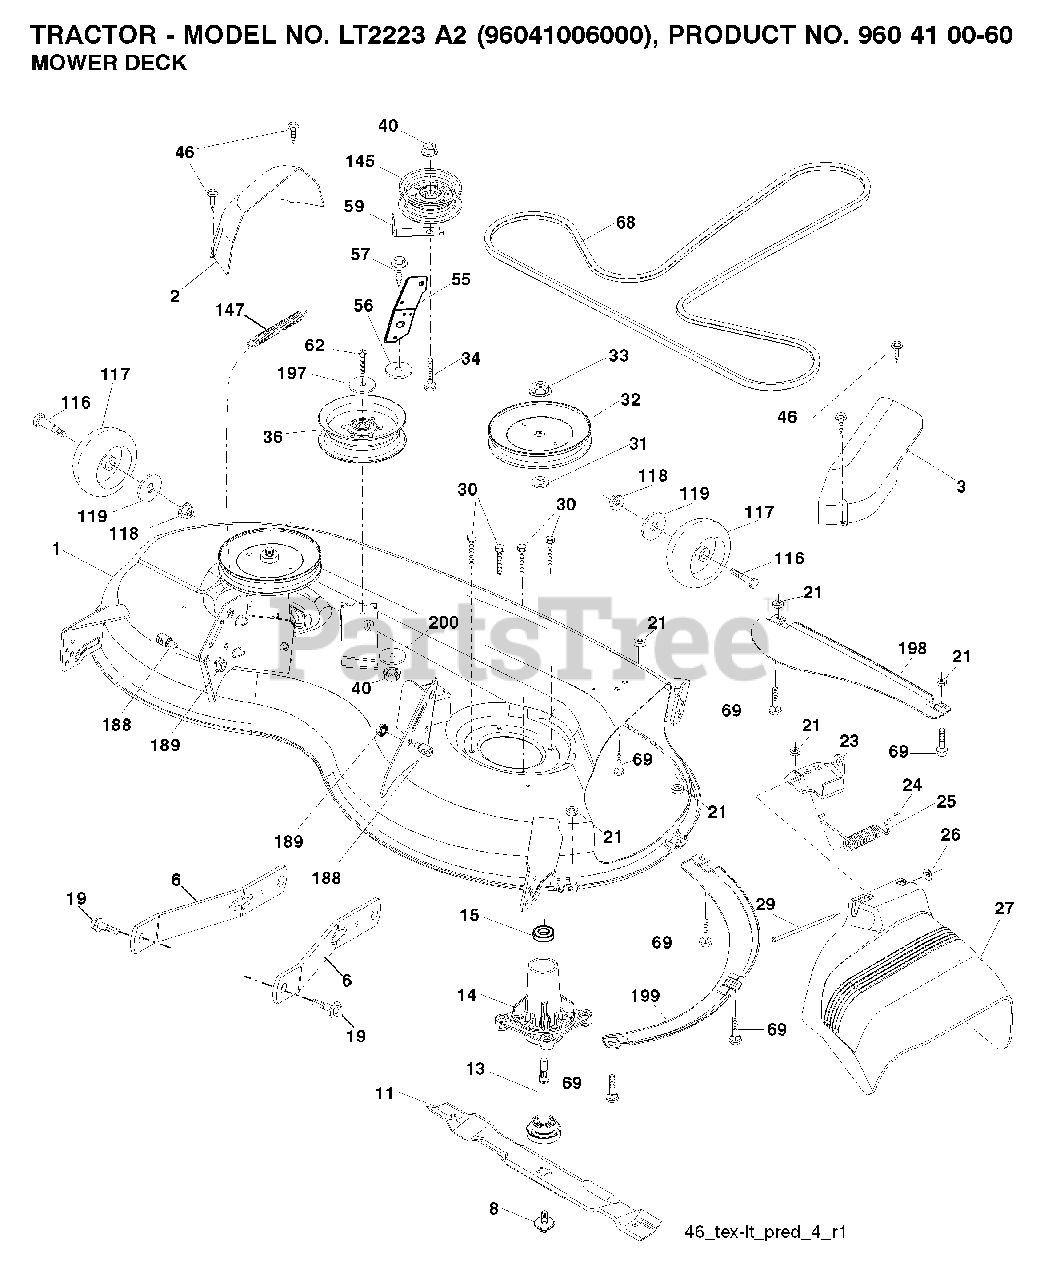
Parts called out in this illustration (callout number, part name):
1	DECK.SVC.46"
2	COVER.MANDREL.LH.46"
3	COVER MANDREL RH
6	ARM.SUSPENSION.MOWER.R
8	BOLT.WASHER.ASM.7/16-2
11	BLADE 46" HI LIFT
13	SHAFT.ASM.MDRL.N/GREASE.38
14	HOUSING MANDREL
19	BOLT.SHOULDER
21	LOCKNUT
23	BRKT.DEFLECTOR.38"2005+
24	CAP-SLEEVE LT
25	SPRING.TORSION.DEFLECT
26	NUT PUSH M
27	SHIELD.DEFLECTOR.MOWER.46"BLAC
29	ROD.HINGE
30	SCREW, WASHER HEAD
31	WASHER.SPACER.MANDREL
32	PULLEY.MANDREL.5.438.PD
33	NUT.FLANGE.LOCK.TOP
34	BOLT.3/8-16X1.50
36	PULLEY.IDLER.48"PRIMARY
40	NUT LOCK FLG 3/8-16 UNC
46	SCREW.1/4-20X5/8
55	IDLER.ARM
56	SPACER.RETAINER
57	SCREW 3/8-16X1
59	GUARD, BELT
62	BOLT-HEX EAK
68	V BELT
69	BOLT
116	BOLT.SHOULDER.3/8-16X3-5/8
117	WHEEL. GUAGE RALLY
118	NUT LOCK FLG 3/8-16 UNC
145	PULLEY.IDLER.2006
147	SPRING.MOWER.DRIVE.ELECTRIC
188	STUD.FASTNER.W/ANTI-ROTATE
189	NUT LOCK HEX FLANGE 5/16-18
197	WASHER
198	BAFFLE CENTER FRONT
199	BAFFLE FRONT RH
200	WASHER 12/32X2X10GA
